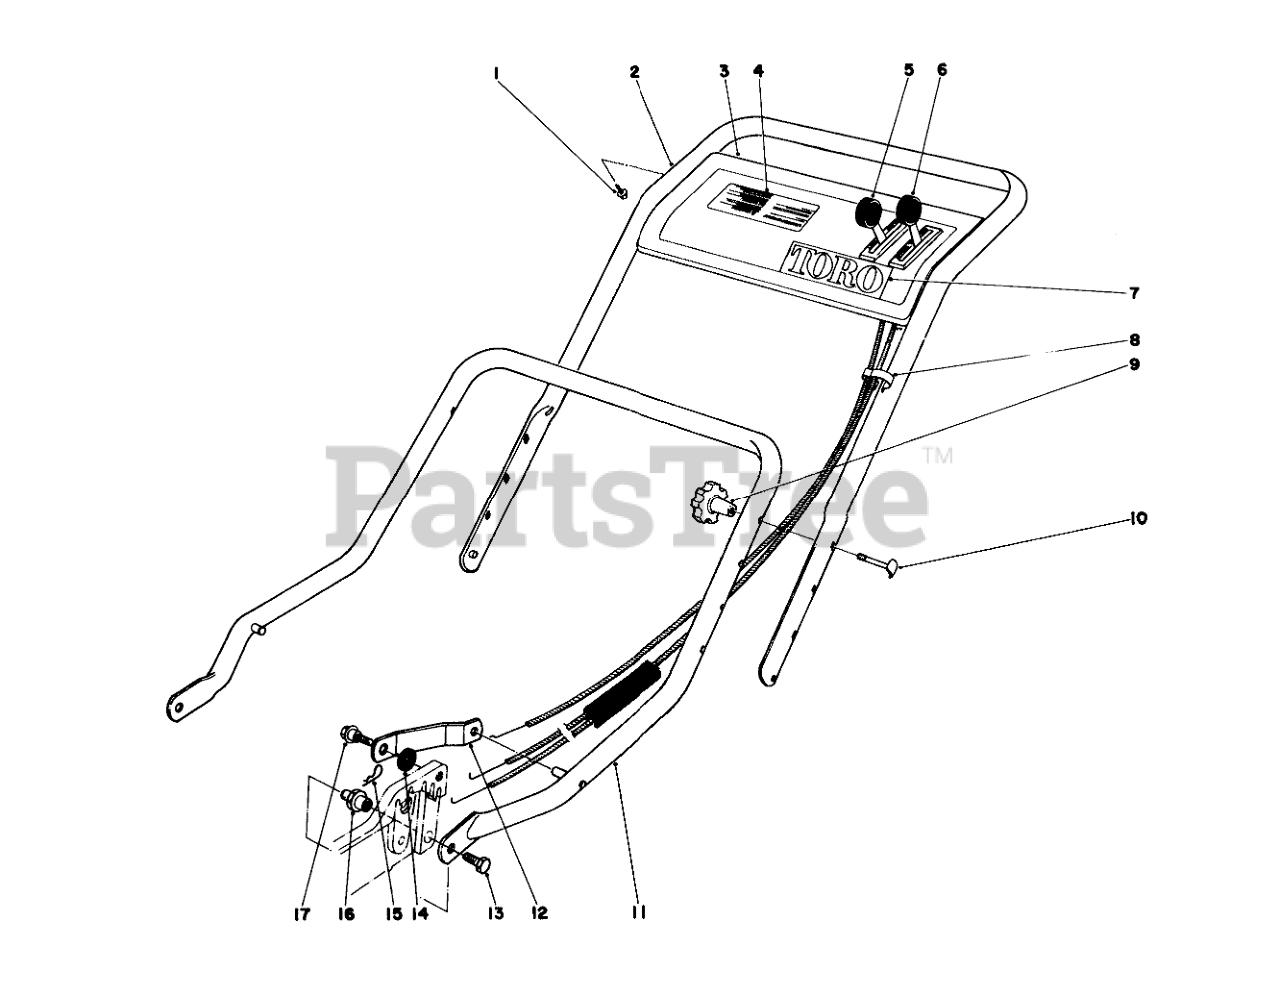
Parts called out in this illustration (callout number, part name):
1	SCREW-HWHTF
2	Upper Handle
3	Control Plate
4	Decal Control Plate
5	Control-Throttle
6	Control-Traction
7	TORO LOGO DECAL
8	BOWDEN CLIP
10	HANDLE SCREW
11	Lower Handle
12	HANDLE LATCH
13	SCREW-HH
14	SPACER
15	PIN-COTTER, HAIR
16	HANDLE PIVOT NUT
17	SCREW-SHOULDER
